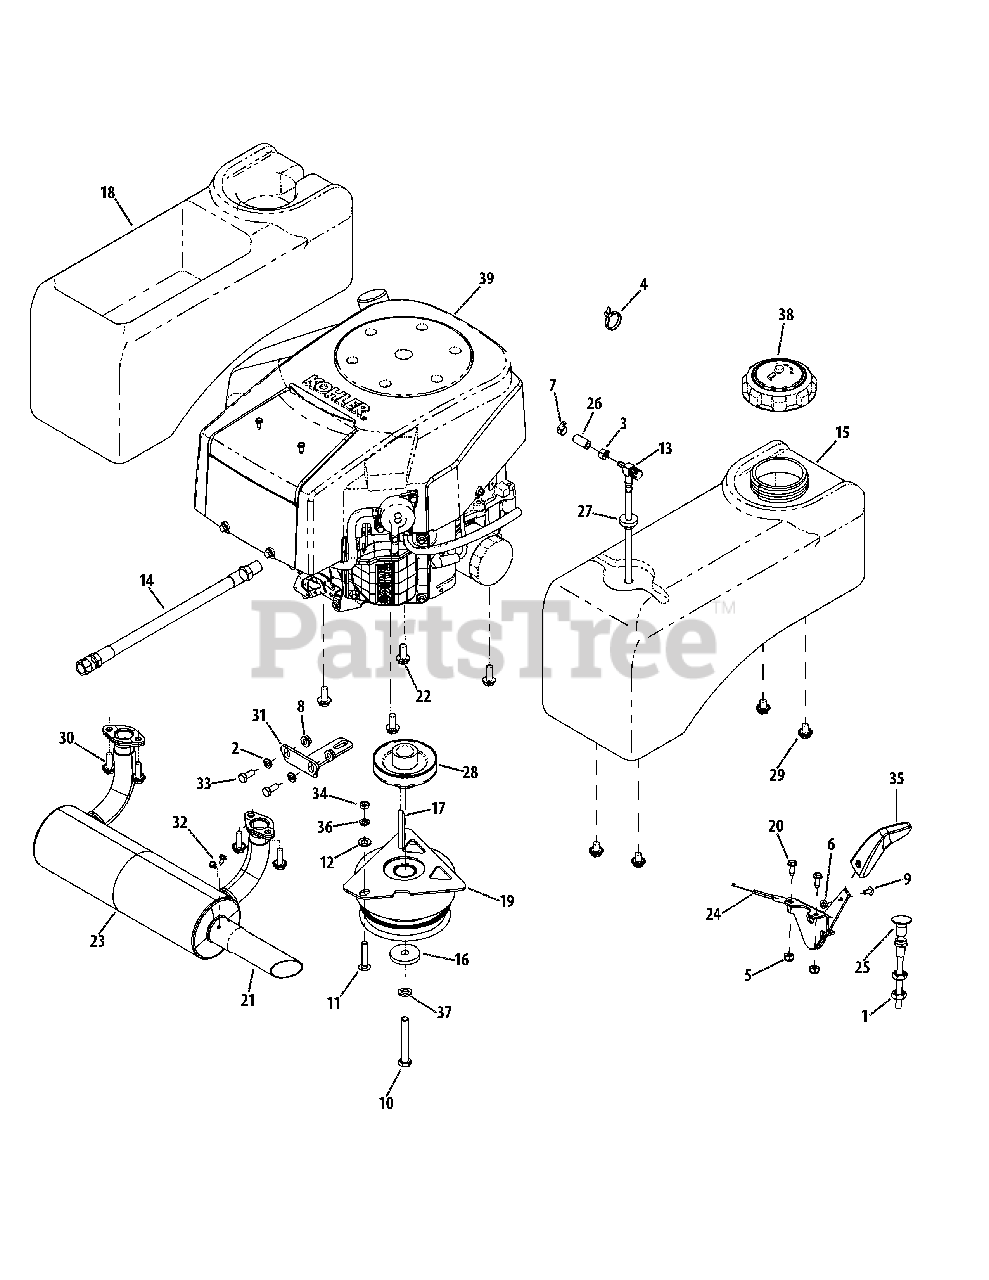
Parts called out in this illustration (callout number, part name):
1	Jam Nut, 3/8-24
2	Washer, .344 x .688 x .063
3	Hose Clamp, .490
4	Cable Tie
5	Nylock Nut, #10-32
6	Nut, #8-32
7	Hose Clamp, .250-.625
8	Flange Counterlock Nut, 5/16-18
9	Machine Screw, #8-32 x .356
10	Hex Screw, 7.16-20 x 3.00
11	Carriage Bolt, 5/16-18 x 1.75
12	Washer, .406 x .750 x .063
13	Fuel Pick-Up Fitting
14	Oil Drain Hose
15	Fuel Tank
16	Washer, .438 x 1.745 x .250
17	Bevel Key, .250 x .250 x 2.75
18	Utility Bin
19	PTO
20	Flange Screw, #10-32 x .500
21	Straight Exhaust Pipe
22	Flange Screw, 3/8-16 x .875
23	Muffler
24	Throttle Control Cable
25	Choke Cable
26	Fuel Hose, 1/4
27	Fuel Tank Grommet
28	Transmission Drive Pulley
29	Hex Flange Screw, 3/8-16 x .500
30	Hex Flange Screw, 5/16-18 x 1.0
32	Hex Washer Screw, #10-16 x 0.500
33	Hex Screw, 5/16-18 x .75
34	Jam Nut, 5/16-18
35	Throttle Control Knob
36	Lock Washer, 5/16
37	Lock Washer, 7/16
39	Kohler SV715-3025 Engine
39	Kohler SV710-0035 Engine
39	Kohler SV720-3044 Engine
